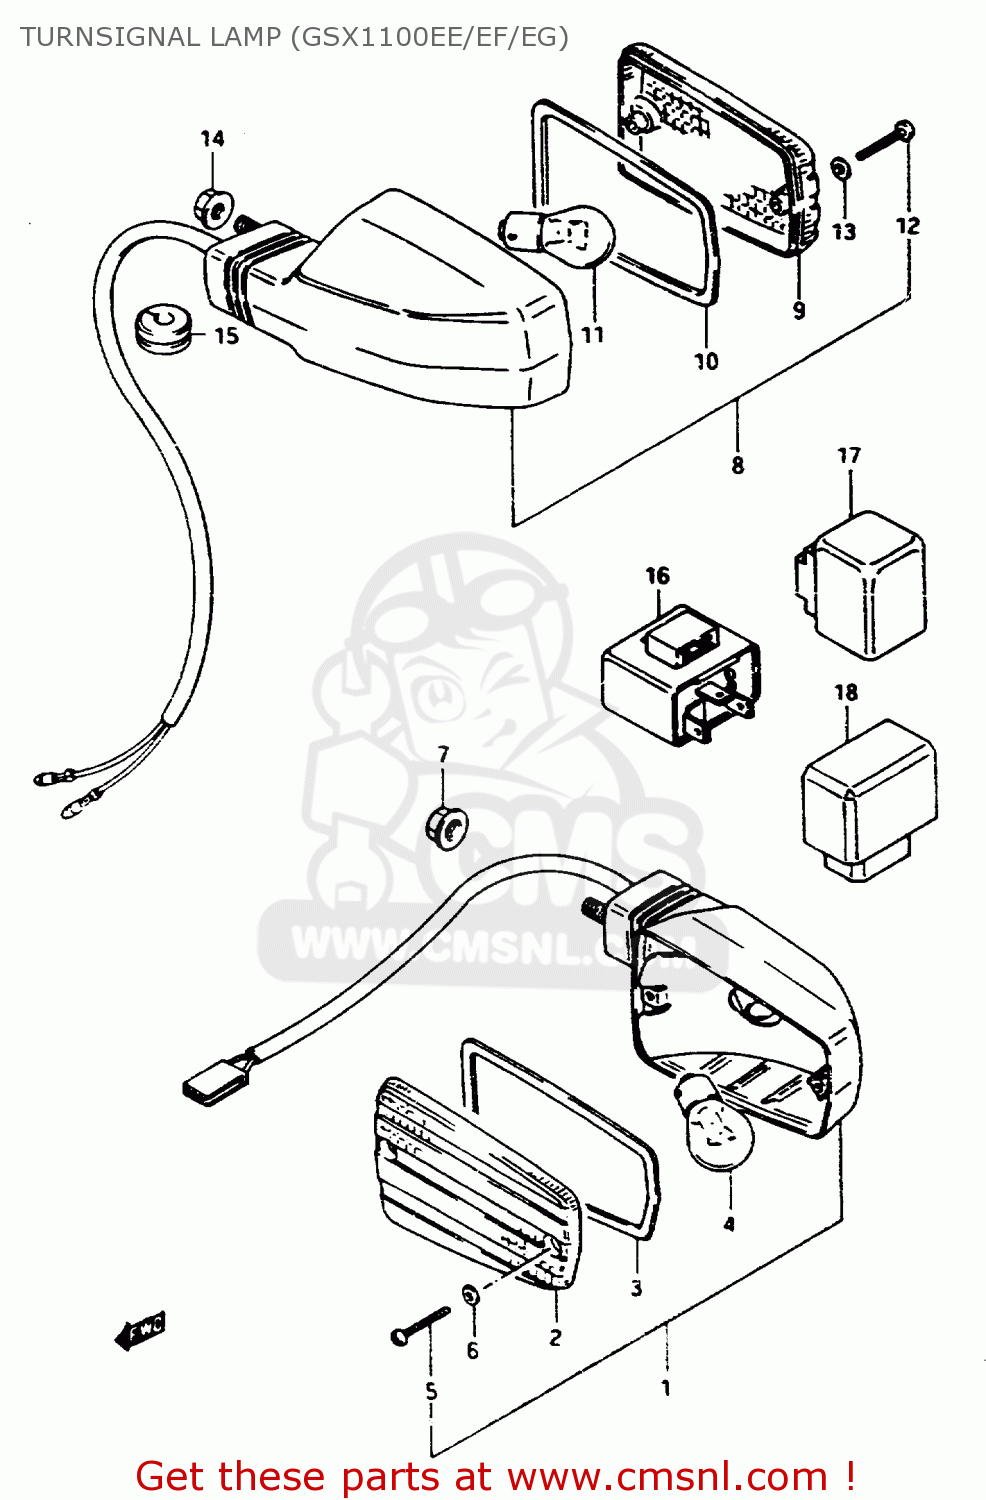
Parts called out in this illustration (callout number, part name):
1	LAMP ASSY, FRONT TURN SIGNAL
2	LENS
3	GASKET (NAS)
4	BULB(12V21W)
5	SCREW
6	GASKET (NAS)
7	NUT
8	LAMP ASSY, REAR TURN SIGNAL
9	LENS
10	GASKET (NAS)
11	BULB(12V21W)
12	SCREW
13	GASKET (NAS)
14	NUT
15	GROMMET
16	RELAY ASSY,TURNSIGNAL
17	RELAY ASSY,TUR
18	UNIT,TURN SIGNAL CONTROL
